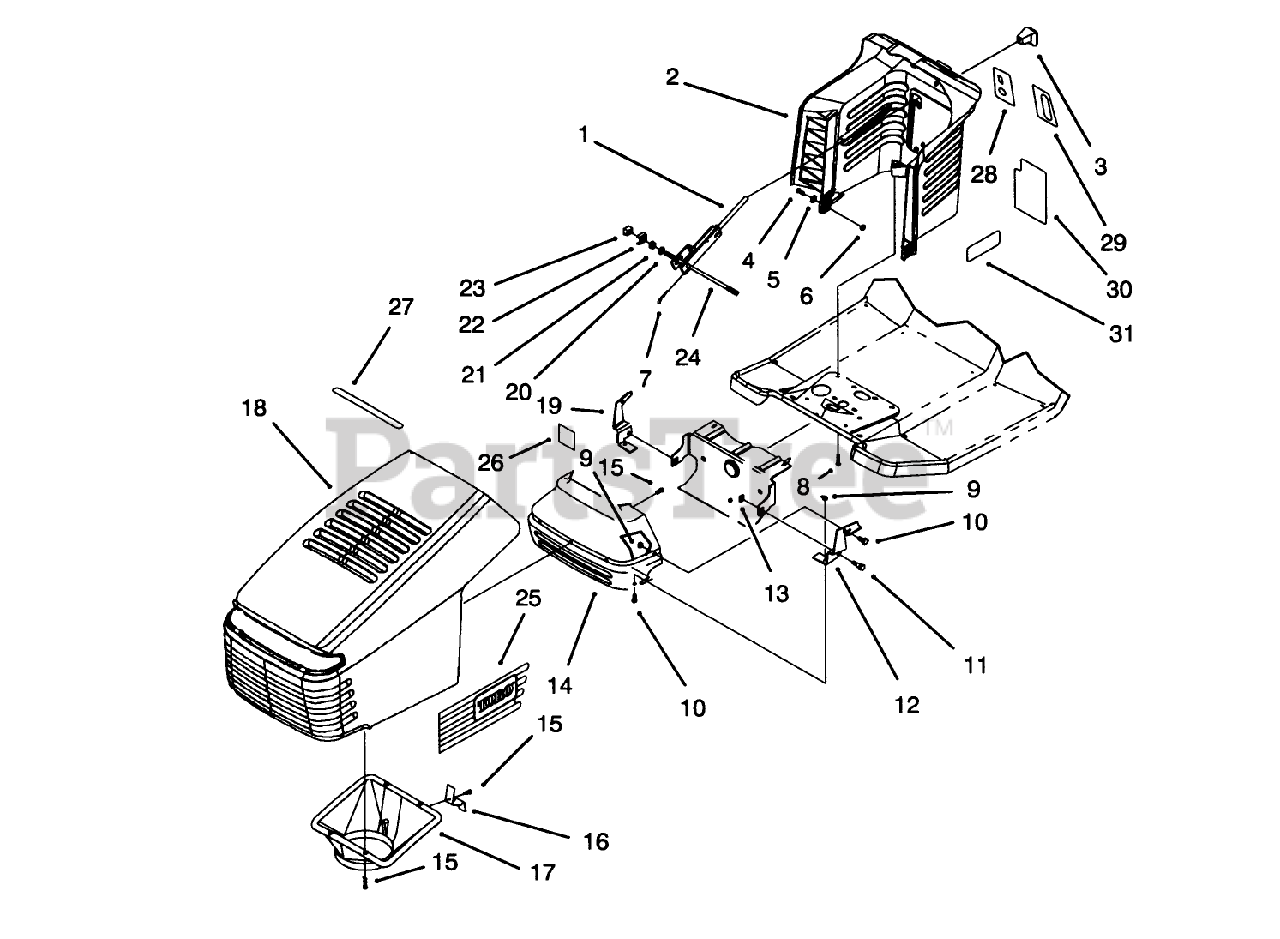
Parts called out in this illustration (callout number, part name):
3	SHIFT KNOB
4	SCREW-HH
5	WASHER-PLAIN
6	NUT-LOCK, NI
8	SCREW-PLASTITE
9	NUT-LOCK, NI
10	SCREW-HH
11	BOLT-SHOULDER
13	NUT-RETAINER
15	SCREW-PLASTITE
16	HOOD LATCH
17	DUCT-AIR
20	WASHER-FLAT
21	NUT-FLANGE
22	ROD-CLAMP PIVOT
24	ROD-TOWER PIVOT
25	DECAL - HOOD RIGHT
26	PICK AS EACH
27	DECAL-AIR DUCT
28	DECAL-IGNITION/LIGHTS
29	DECAL-THROTTLE/CHOKE
30	DECAL-DECK, ENGAGE
